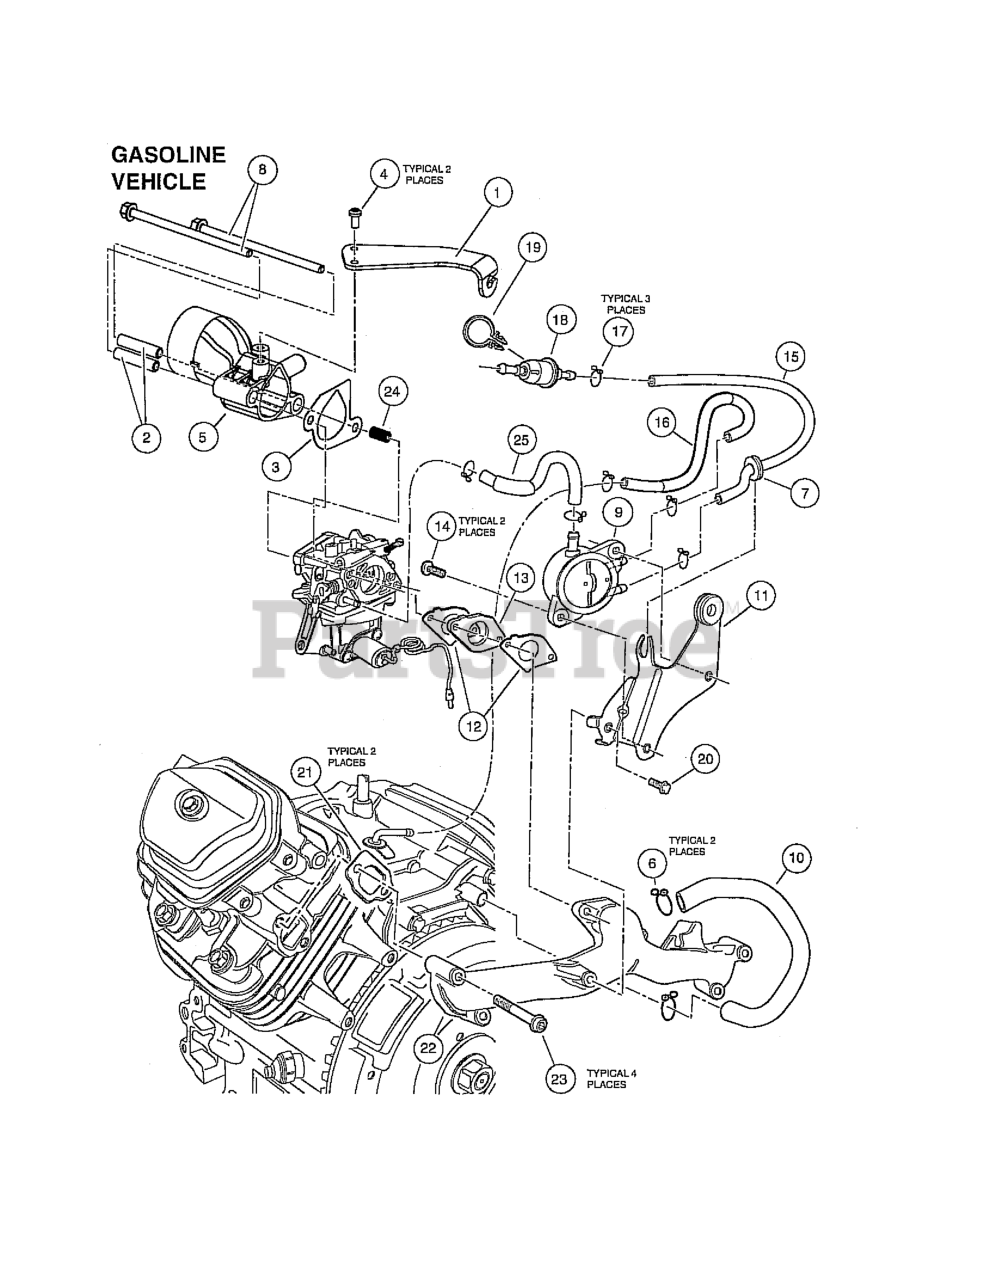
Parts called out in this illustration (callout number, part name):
1	BRACKET, CHOKE CABLE
2	INSERT, ADAPTER, CARBURETOR
3	GASKET, ADAPTER, CARBURETOR
4	SCREW TAPPING, M5X0.8X10
5	ADAPTER, INTAKE HONDA GX620
6	CLIP, BREATHER TUBE
7	GROMMET, RESERVE TANK
8	BOLT, FLANGE, M6 X 1 X 120
9	PUMP ASSY., FUEL, SUP
10	TUBE, BREATHER
11	STAY,FUEL PUMP
12	GASKET, CARBURETOR
13	INSULATOR, CARBURETOR
14	SCREW-WASHER, M6 X 16
15	TUBE B, FUEL
16	TUBE, DIAPHRAGM
17	CLIP, TUBE, B10
18	FILTER FUEL
19	CLIP, WIRE HARNESS
20	BOLT, FLANGE, M6 X 11 X 4
21	GASKET, IN. MANIFOLD
22	MANIFOLD, IN
23	BOLT, SOCKET, M8 X 1.25 X 45
24	SPRING, CONTINUITY, SOLENOID
25	TUBE A, FUEL
